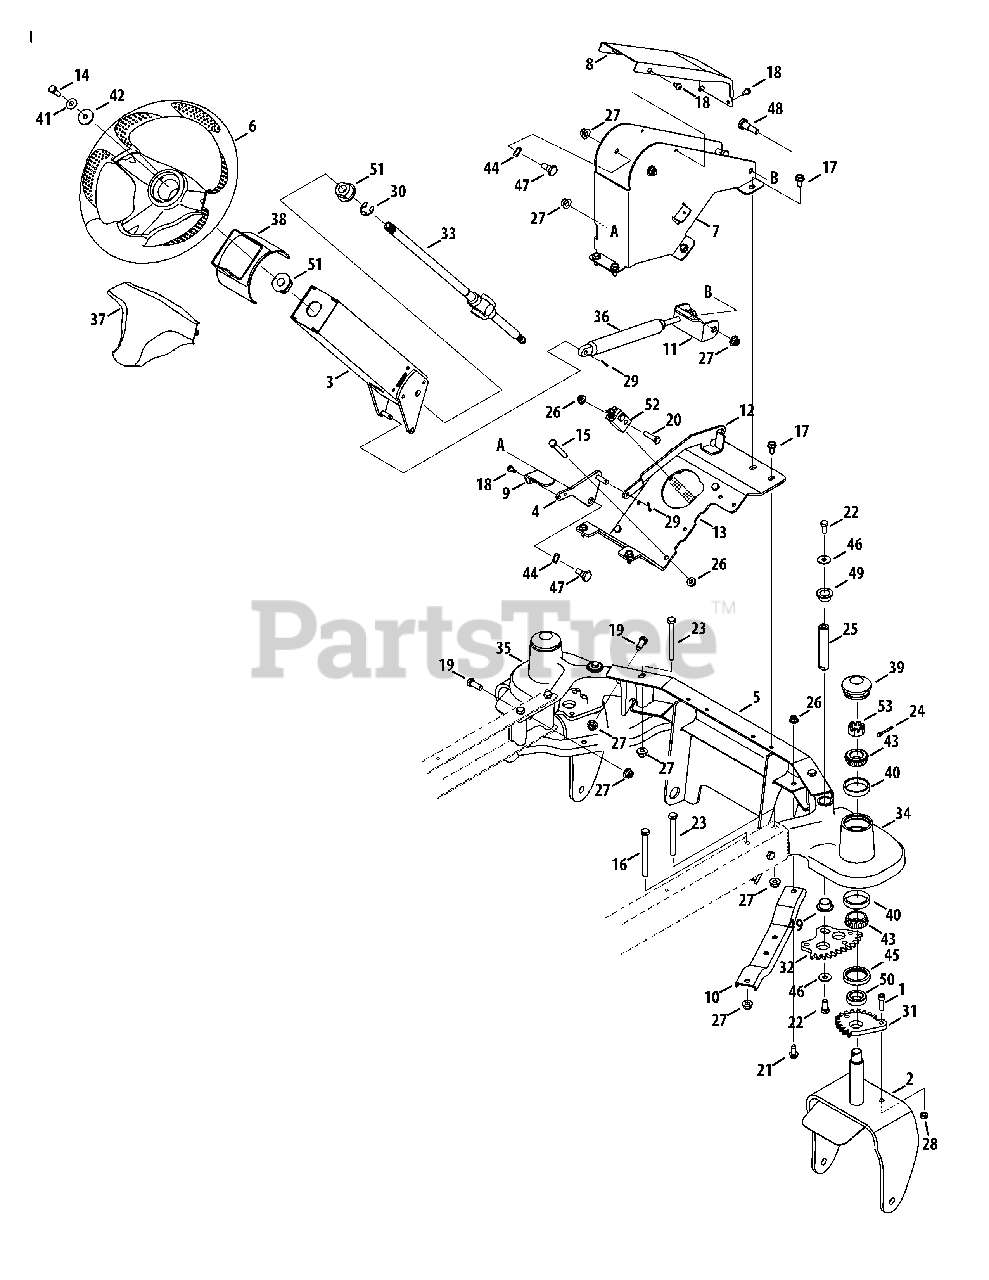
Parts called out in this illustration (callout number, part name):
1	Socket Head Screw, 5/16-18 x 1.00
2	Caster Bracket Assembly
3	Upper Steering Column Assembly
4	Tilt Release Pedal Assembly
5	Front Bumper Frame Assembly
6	Steering Wheel Assembly
7	Lower Steering Wheel Column
8	Lower Column Cover
9	Tilt Steering Pedal
10	Front Frame Brace
11	Damper Pivot Lower Bracket
12	Tilt Action Lever
13	Steering Mount Box Plate
14	Hex Screw, 5/16-18 x 1.00
15	Hex Screw, 5/16-18 x 2.25
16	Hex Screw, 3/8-16 x 4.00
17	Hex Washer Screw, 5/16-18 x .750
18	Screw, 1/4-20 x .5
19	Hex Screw, 3/8-16 x 1.00
20	Hex Screw, 5/16-18 x 1.25
21	Hex Washer Screw, 5/16-18 x 750
22	Hex Screw, 5/16-18 x .75
23	Hex Screw, 3/8-16 x 3.50
24	Cotter Pin
25	Pivot Gear Steering Shaft
26	Flange Lock Nut, 5/16-18
27	Flange Lock Nut, 3/8-16
28	Hex Lock Nut, 5/16-18
29	Cotter Pin, 3/32 x .750
30	E-Ring, .750
31	13-Tooth Variable Spur Gear
32	12-Tooth Variable Gear
33	Steering Shaft
34	RH Tpr. Bearing Caster Pivot Axle
35	LH Tpr. Bearing Caster Pivot Axle
36	Locking Damper Cylinder, 80MM
37	Steering Wheel Cover
38	Column Cover
40	Bearing Cup
41	Bell Washer, .340 x .872 x .060
42	Flat Washer, .330 x 1.25 x .120
43	Cone Bearing
44	Wave Washer, .510 x.750 x .017
45	Seal
46	Flat Washer, .344 x 1.00 x .063
47	Shoulder Bolt, 3/8-16 x .496 x .336
48	Shoulder Screw, 3/8-16 x .50 x .66
49	Flange Bearing, 3/4 x .52
50	Seal Ring
51	Flange Bearing, .630 x 1.50
52	Steering Shaft Block
53	Slotted Nut
